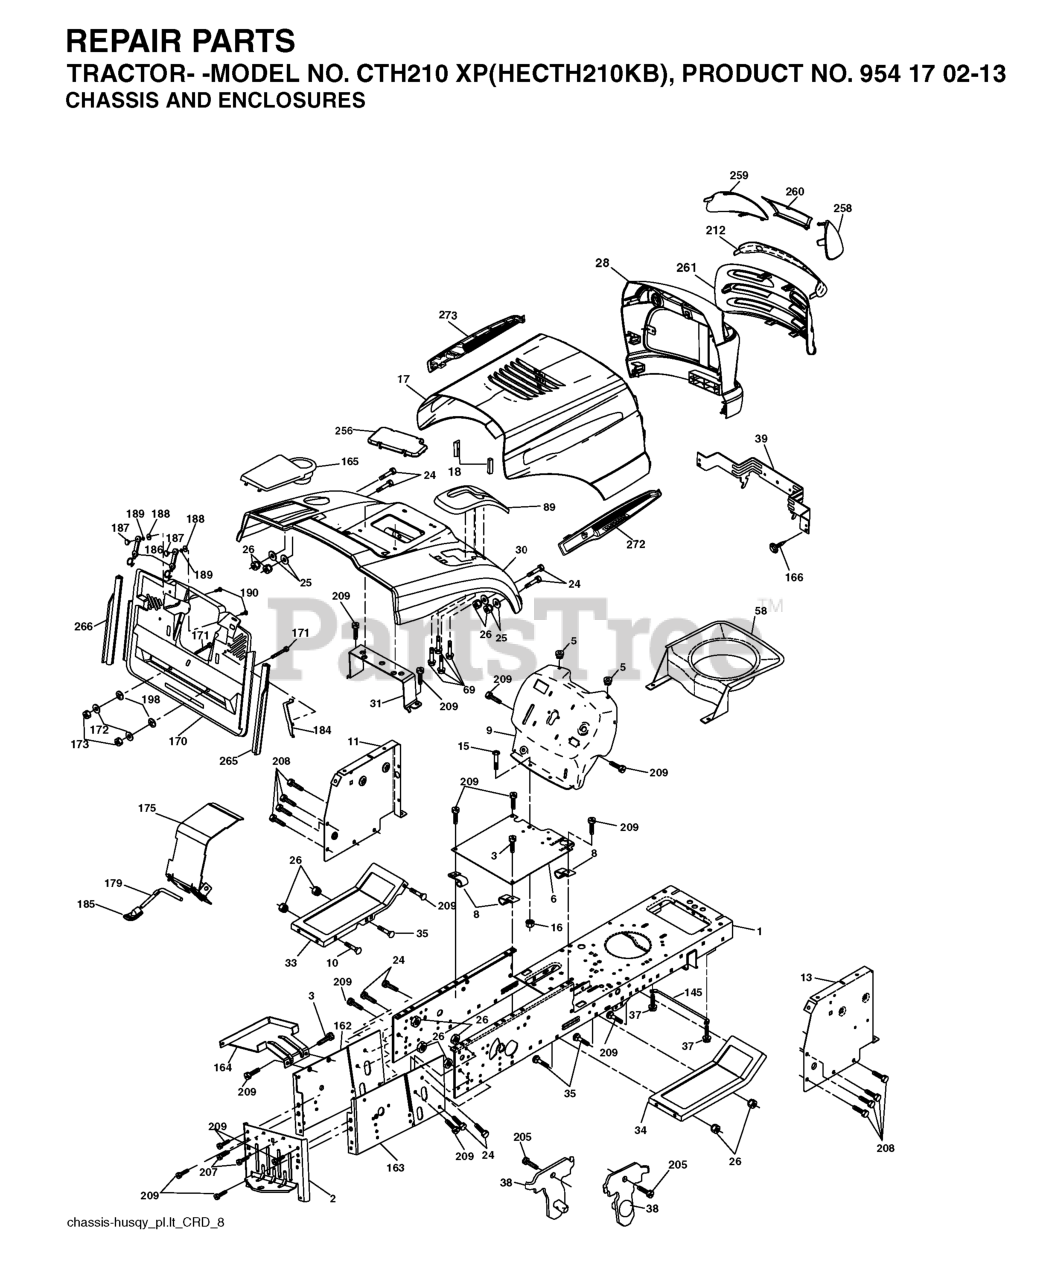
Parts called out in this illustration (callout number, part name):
2	DRAWBAR
3	SCREW 3/8-16X3/4
5	BUMPER.RUBBER.HOOD
6	PLATE
8	CLIP,INSULATOR
10	BOLT D
11	PANEL.DASH.LH.LTX
13	PANEL ASM, DASH RH
15	Screw, Machine, Truss Head 5/16-18 UNC x 3/4
16	NUT
17	VENT.HOOD.LASER.III
18	BUMPER.HOOD.LARGE.1.75"
25	WASHER
26	NUT
31	BRACKET SUPPORT FENDER
33	FOOTREST PNT LH
34	FOOTREST PNT RH
37	Screw 5/16-18 x 1/2 Hex, Self Tapping 5/16-18 x 1/2
38	BRACKET ASM PIVOT MOWER REAR
39	BRACKET PIVOT LASER
69	SCREW.HI-LO.CONSOLE
89	COVER.BATTERY.CRD.GREY
145	ROD PIVOT CHASSIS/HOOD
162	BRACKET
163	BRACKET EXTEN CHASSIS RH CRD
165	RP.COVER.BATTERY.CRD.GREY
166	SCREW
172	WASHER
175	DOOR TRAP
179	ROD PIVOT FBI
184	BRACKET.ACTUATOR.BAGGER.SRD
186	LATCH ASSY
187	WELDNUT
189	LOCKWASHER #10
190	SCREW
207	SCREW, 5/16-18 X 1/2
208	SCREW 3/8-16X1/2
209	SCREW, 3/8-16X3/4
212	INSERT.LENS.REFLECTIVE
256	COVER FENDER CRD
258	LENS LH
259	LENS LH
260	COVER.LENS.HUSQ.LASER
265	SEALING
266	SEALING
272	VENT.HOOD.LASER.
273	VENT.HOOD.LASER.
